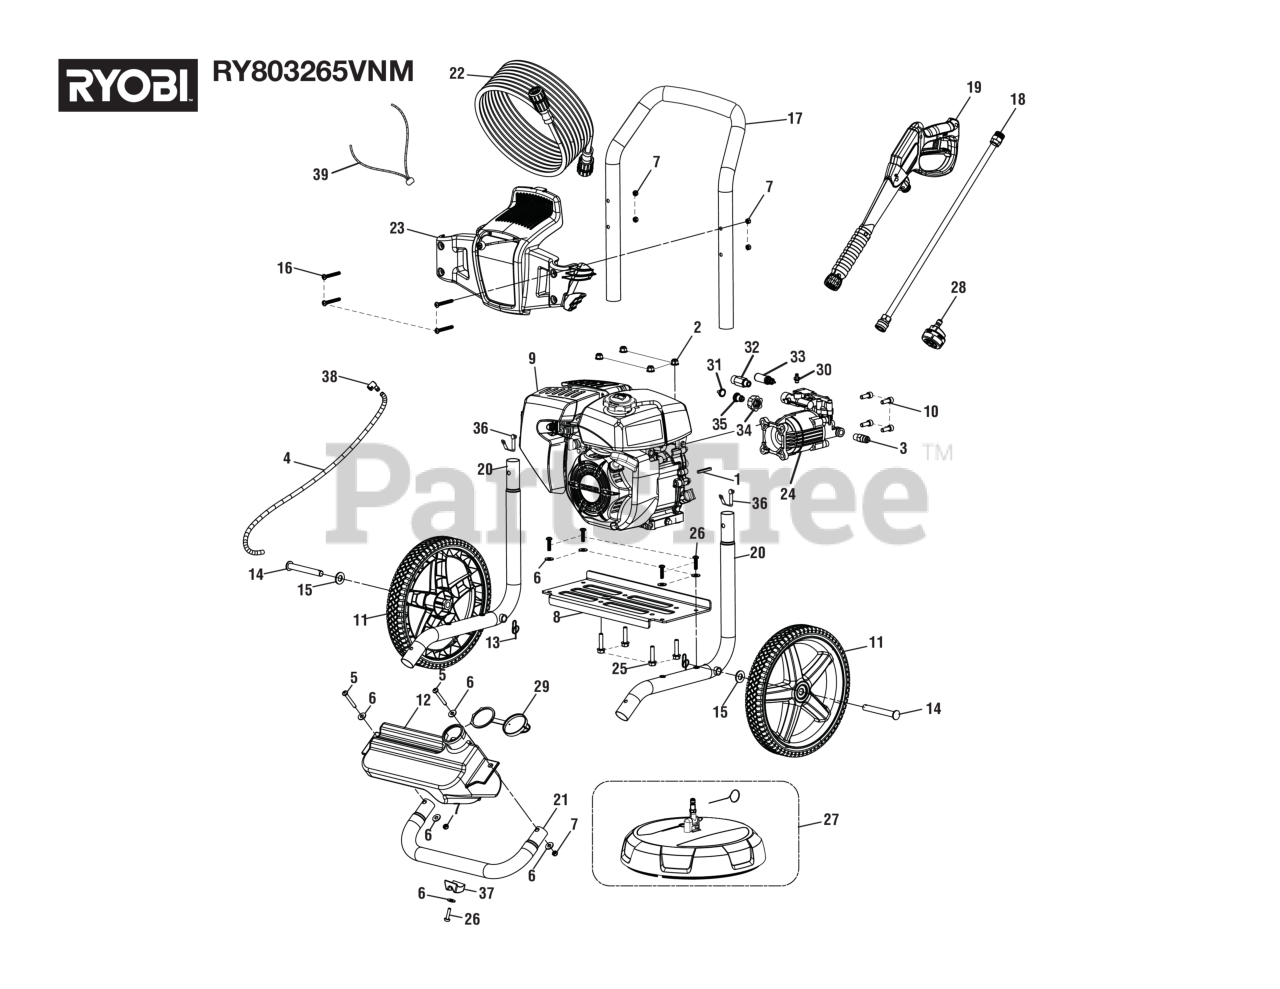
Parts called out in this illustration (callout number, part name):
1	Output Shaft Key (3/16 in. x 40 mm)
2	Lock Nut (M8 x 1.25 mm, Flange)
3	Thermal Release Valve.
4	Chemical Siphon Tube
5	Screw (M6 x 1 x 48 mm, T30 Torx Pan Hd.)
6	Washer (1/4 in.)
7	Lock Nut (M6 x 1)
8	Engine Plate
9	Motor
10	Screw (5/16-24 x 23 mm, Hex Soc. Cap Hd.)
12	Soap Tank
13	Hitch Pin
15	Washer (1/2 in.)
16	Bolt (M6 x 48 mm, Button Hd.)
17	Handle Assembly
18	Extension Wand
19	Trigger Handle Assembly
20	Frame Assembly
21	Front Frame Assembly (Inc. Key No. 33)
22	Hose (35 ft.)
23	Performance Panel
24	Pump (Inc. Key Nos. 57-62)
25	Bolt (M8 x 36 mm, Hex Flange Hd.)
26	Screw (M6 x 1.25in., T30 Torx Pan Hd.)
27	Surface Cleaner
28	5-in-1 Nozzle
29	Detergent Tank Cap
30	Detergent Injector Assembly
31	Filter Screen (Pump Inlet)
32	Outlet Tube
33	Unloader Valve Assembly
34	Inlet Filter Adapter/Brass Insert
35	Inlet Filter Connector
36	Lock Button w/Spring Clip.
37	Rubber Foot
38	Soap Hose Inlet Adapter
39	Bungee Cord and Bead Assembly
